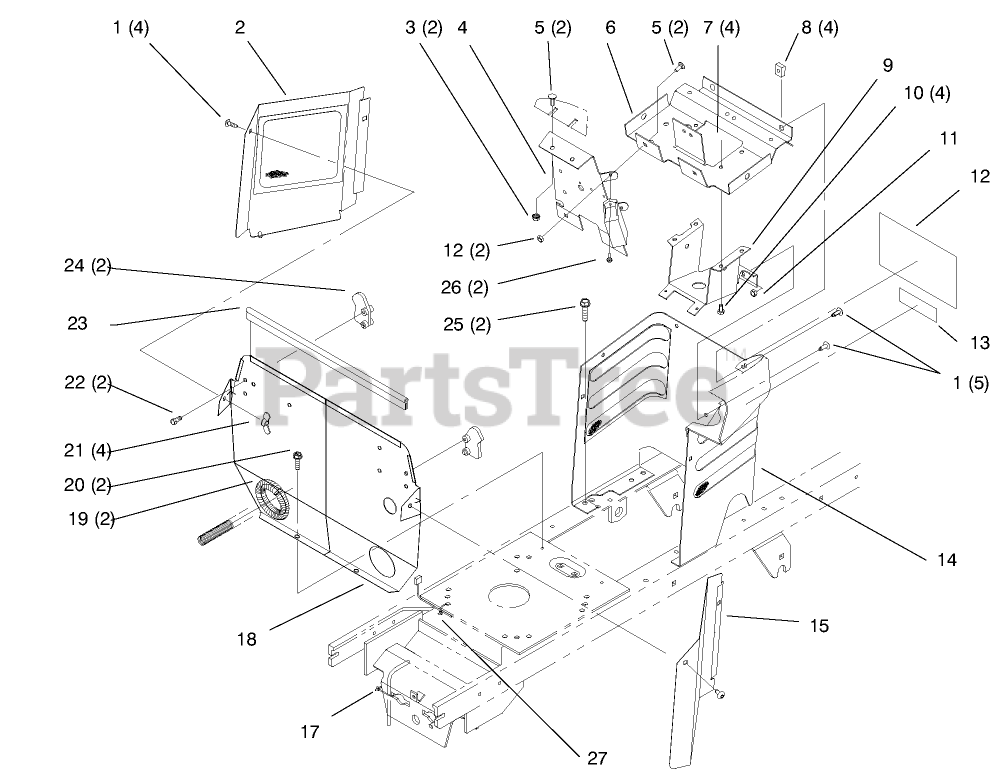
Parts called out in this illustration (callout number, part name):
1	SCREW-HH
2	RH SIDE COVER ASM
3	NUT-KEPS
4	SUPPORT - DASH
5	SCREW-CARR
6	SUPPORT-DASH
7	NUT-HEX
8	NUT RETAINER - J TYPE
9	BRACKET-COLUMN, LOWER
10	SCREW-HH
11	NUT-LOCK, NI
12	DECAL - DANGER
13	DECAL-INSTRUCTION
15	LH COVER ASM
16	DECAL - 265-6
18	FIREWALL
19	COVER-SHAFT, DRIVE
20	SCREW-HWH
21	NUT-WING
22	SCREW-PLASTITE
23	TRIM-SEAL, FIREWALL
24	LATCH-HOOD
25	SCREW-HWHTF
26	SCREW-PPHTF
